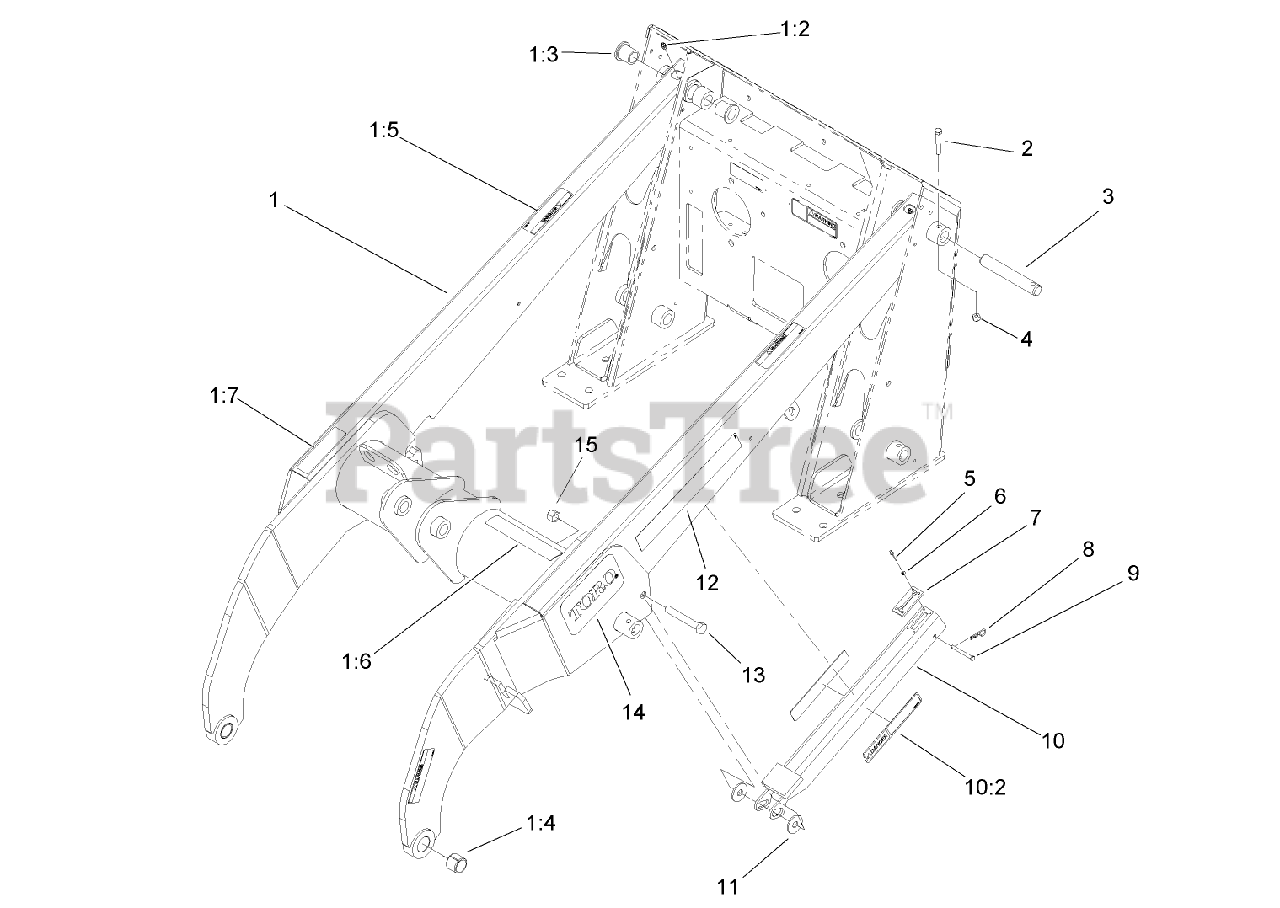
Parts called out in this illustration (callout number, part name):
1	LOADER ARM ASM
1:2	FITTING-GREASE
1:3	BUSHING
1:4	BUSHING-TENSION
1:5	DECAL-PINCH
1:6	DECAL-CAUTION
1:7	DECAL-CAUTION
2	SCREW-HH
3	PIN-LOCKING
4	NUT-LOCK, NI
5	RIVET-BLIND
6	WASHER-FLAT
7	STOP-RUBBER
8	PIN-COTTER
9	PIN-CLEVIS
10	LOCKING ARM ASM
10:2	DECAL-DANGER
11	WASHER-RUBBER
13	SCREW-HH
15	NUT-LOCK, NI
